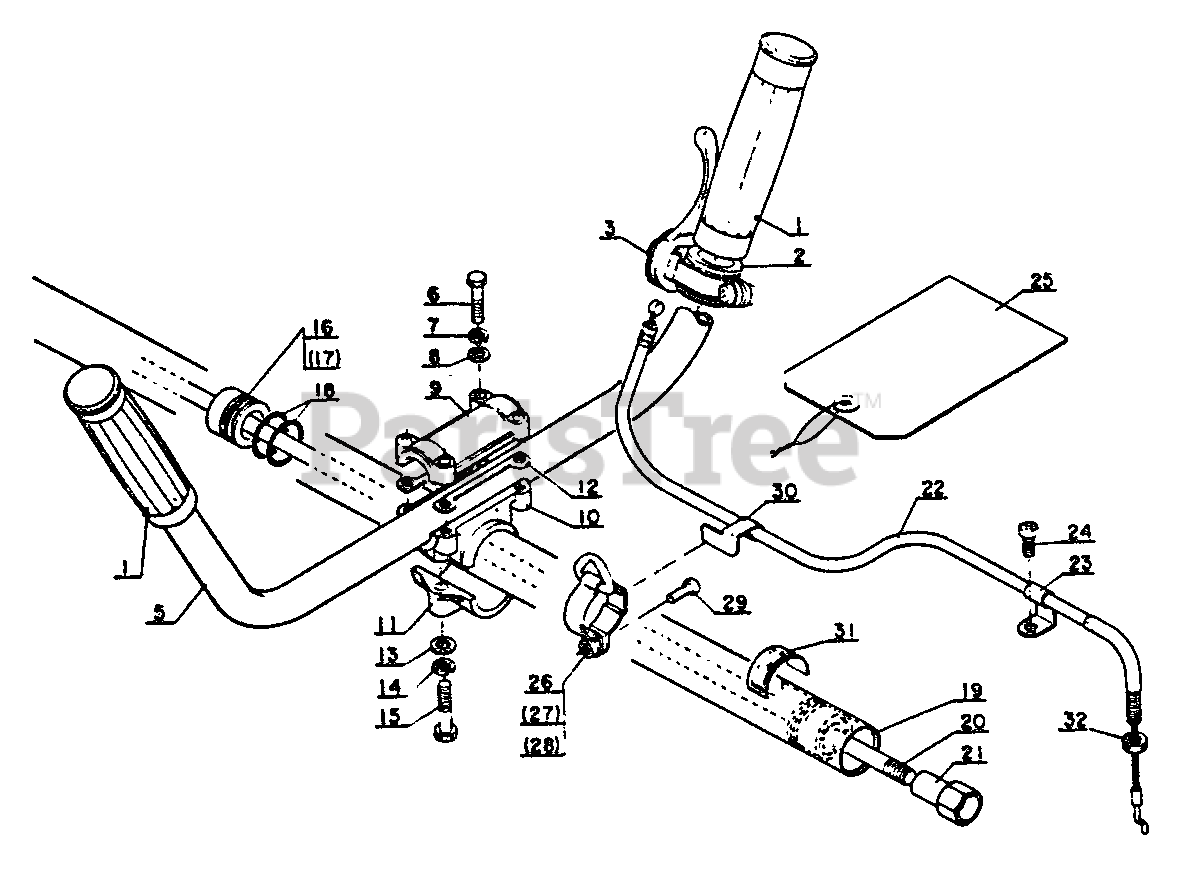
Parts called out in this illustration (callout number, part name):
1	GRIP, HANDLE - LEFT
3	LEVER, THROTTLE
5	HANDLE
6	BOLT - 5X25
7	LOCKWASHER - 5
8	WASHER - 5
9	HANDLE BRACKET KIT
10	HANDLE BRACKET KIT
11	HANDLE BRACKET KIT
13	WASHER - 6
14	LOCKWASHER - 6
15	BOLT - 6X30
16	STOPPER
18	O-RING - 22
19	PIPE, MAIN
20	DRIVESHAFT
21	CONNECTOR
22	CABLE, THROTTLE
23	CLAMP
24	SCREW - 5X8
31	LABEL - CAUTION
